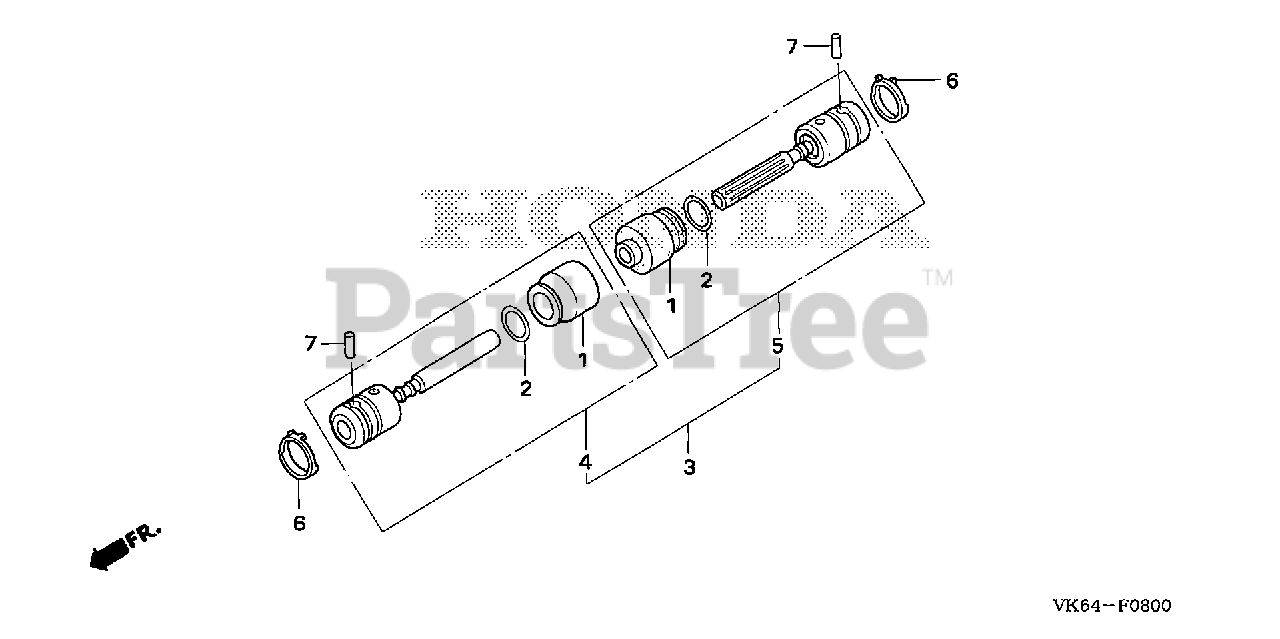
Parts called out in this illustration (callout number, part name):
1	BOOT, JOINT
2	RING, SEAL
3	JOINT ASSY.
4	JOINT SUB-ASSY. (A)
5	JOINT SUB-ASSY. (B)
6	CLIP, CLUTCH SHAFT
7	ROLLER (4X17.8)
